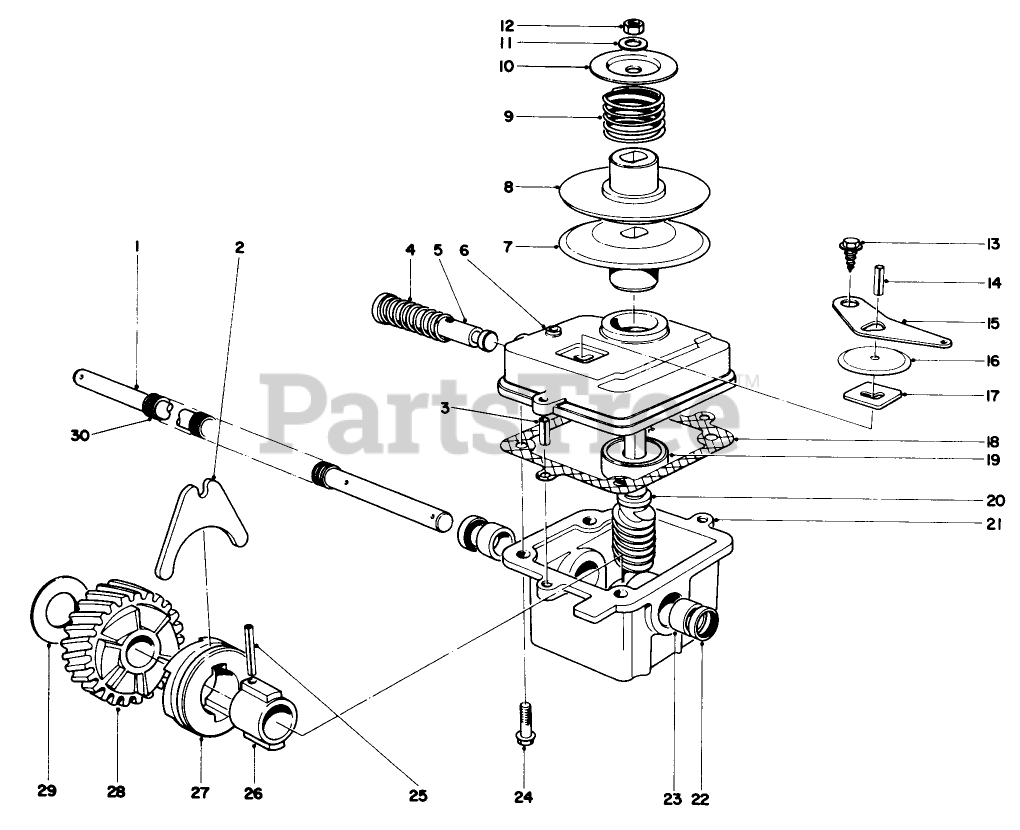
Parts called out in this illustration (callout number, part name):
1	Drive Shaft
2	SHIFTER FORK
3	3/16 X 1/2 ROLL PIN
4	SPRING
5	Shift Rod
6	GEAR CASE COVER
7	LOWER PULLEY HALF
8	UPPER PULLEY HALF
9	COMPRESSION SPRING
10	SPRING RETAINER
11	WASHER-FLAT
12	NUT-HEX, SIDE DEFORM
13	Screw
14	PIN-ROLL
15	SHIFTER ARM
16	TRANS DUST COVER
17	LATCH PLATE
18	GASKET
19	Bearing
20	Shaft-Worm
21	Gear Case (Incl. Ref. #22 & 23)
22	Seal
23	Bushing
24	Screw
25	COIL PIN
26	SLEEVE
27	CLUTCH JAW
29	THRUST WASHER
30	DRIVE SHAFT COVER
